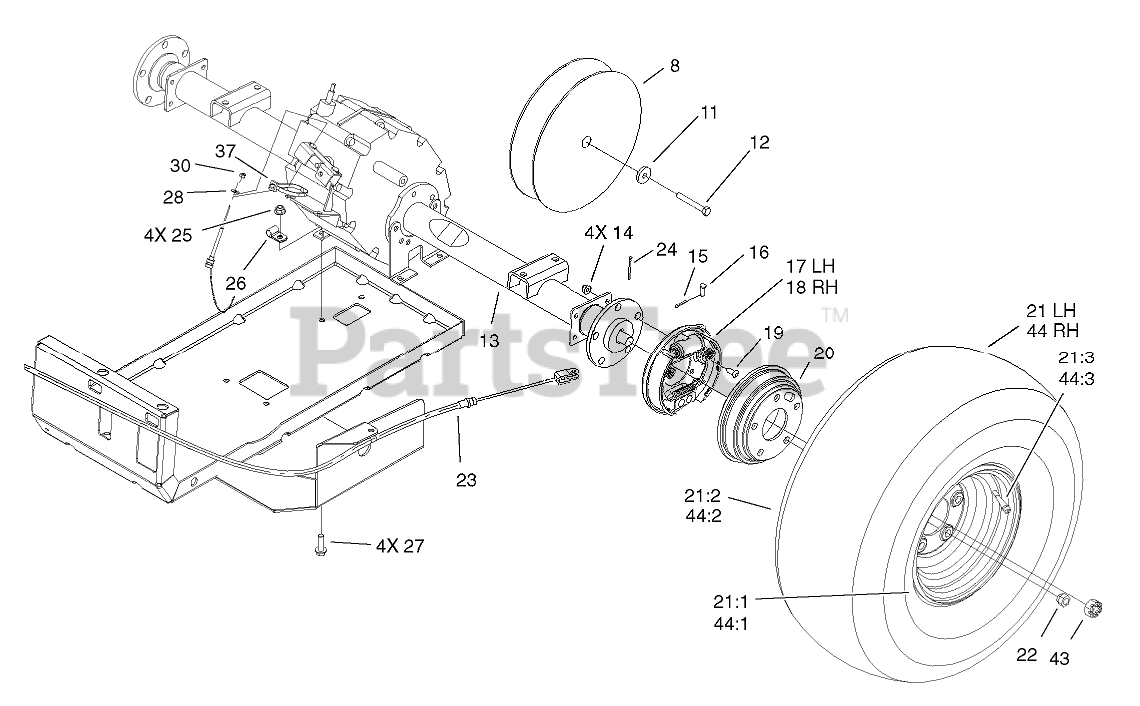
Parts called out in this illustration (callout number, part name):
8	CLUTCH-DRIVEN
11	WASHER-STEPPED
12	Screw-HH
13	Transaxle
14	NUT-HF, NI
15	PIN-COTTER
16	PIN-CLEVIS
17	LH BRAKE ASM
18	RH BRAKE ASM
19	SCREW-HSBH
20	DRUM-BRAKE
21	TIRE AND WHEEL ASM
21:1	WHEEL-5 BOLT
21:3	STEM-VALVE
22	NUT-LUG
23	CABLE-BRAKE, PARK
24	PIN-COTTER
25	NUT-HF, NI
26	R-CLAMP
27	SCREW-HHF
28	WASHER-PLAIN
30	NUT-LOCK, NI
37	TIE-CABLE
43	NUT-CASTLE
44	TIRE AND WHEEL ASM
44:1	WHEEL-5 BOLT
44:3	STEM-VALVE
